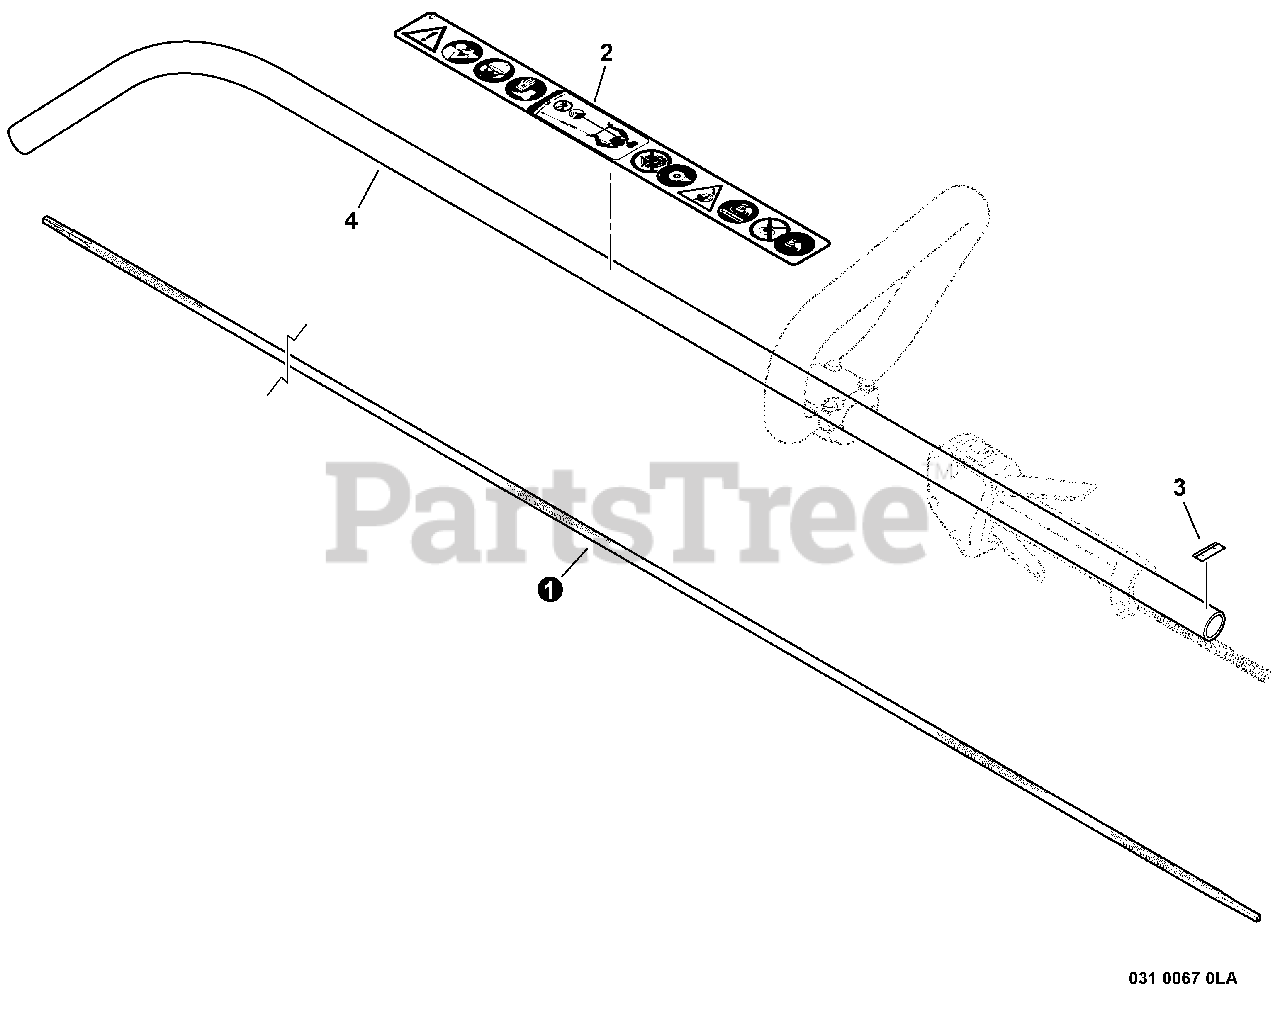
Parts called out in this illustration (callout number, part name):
1	DRIVESHAFT - FLEXIBLE
2	LABEL - CAUTION
3	LABEL - ALIGNMENT
4	PIPE, MAIN
